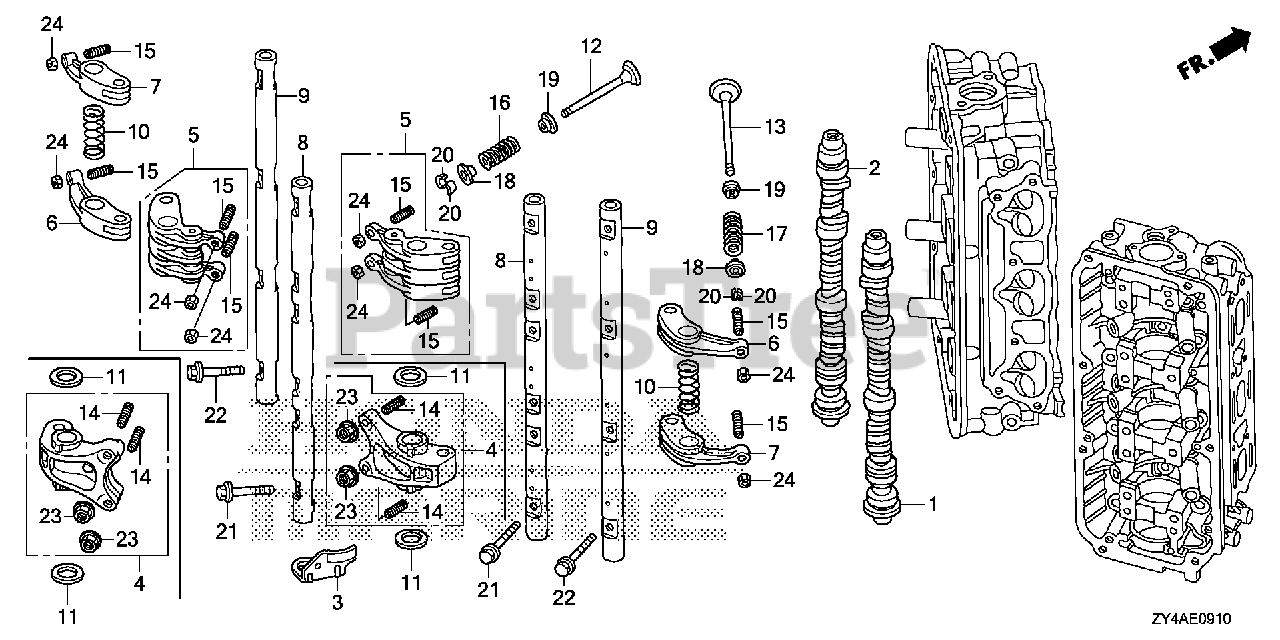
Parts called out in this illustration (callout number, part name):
1	CAMSHAFT, R.
2	CAMSHAFT, L.
3	ARM, FUEL PUMP ROCKER
5	ARM ASSY., IN. ROCKER
6	ARM A, EX. ROCKER
7	ARM B, EX. ROCKER
8	SHAFT, IN. ROCKER ARM
9	SHAFT, EX. ROCKER ARM
10	SPRING, ROCKER ARM
12	VALVE, IN.
13	VALVE, EX.
15	SCREW, TAPPET ADJUSTING
16	SPRING, IN. VALVE (GRAY) (ASSOCIATED SPRING)
17	SPRING, EX. VALVE (YEL/GRN) (ASSOCIATE)
18	RETAINER, VALVE SPRING
19	SEAT, VALVE SPRING
20	COTTER, VALVE (FUJI VALVE)
21	BOLT, FLANGE (8X30)
22	BOLT, FLANGE (8X40)
24	NUT, TAPPET ADJUSTING
